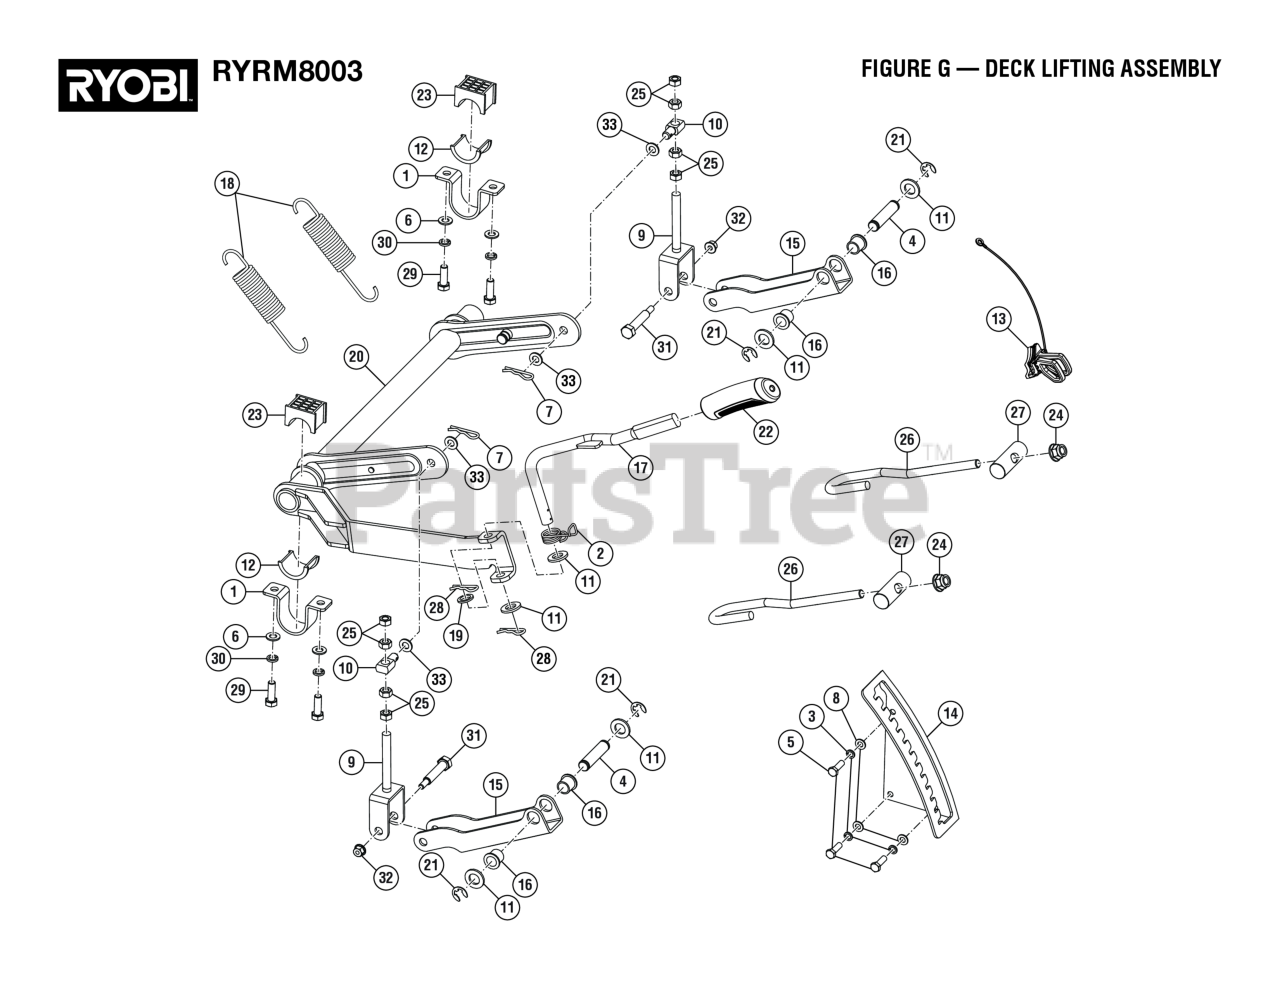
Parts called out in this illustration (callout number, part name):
1	Deck Lift Axle Mount
2	Deck Lift Lever Torsion Spring
3	Washer (OD16 x ID8.4 x 1.6t)
4	Deck Baffle (42 in.)
5	Bolt (M8 x 25 mm, Hex Hd.)
6	Washer (OD20 x ID10.5 x 2t)
7	Cotter Pin
8	Washer (OD16 x ID8.4 x 1.6t)
9	Deck Lift Linkage
10	Hanger Stud
11	Washer (OD30 x ID17 x 3t)
12	Deck Lift Axle Bushing, Bottom
13	Cut Height Memory Plug
14	Detent Plate
15	Deck Lift Linkage
16	Deck Lift Linkage Bushing
17	Deck Lift Lever
18	Deck Lift Spring
19	Deck Lever Int. Washer
20	Deck Lift Axle
21	E-Ring Clip (12 mm)
22	Decklift Handle
23	Deck Lift Axle Bushing,Top
24	Flange Nut (M12)
25	Hex Nut (M12 x 1.75 mm)
26	J-Hook, Front Deck Hanger
27	Front Deck Hanger Pivot Axle
28	Lock Pin (16 mm)
29	Hex Head (M10 x 30 mm)
30	Lock Washer (M10)
31	Deck Linkage Shoulder Bolt
32	Flange Nut (M8) (For Drive Motor Controller V)
33	Washer (OD24 x ID13 x 2.5t)
